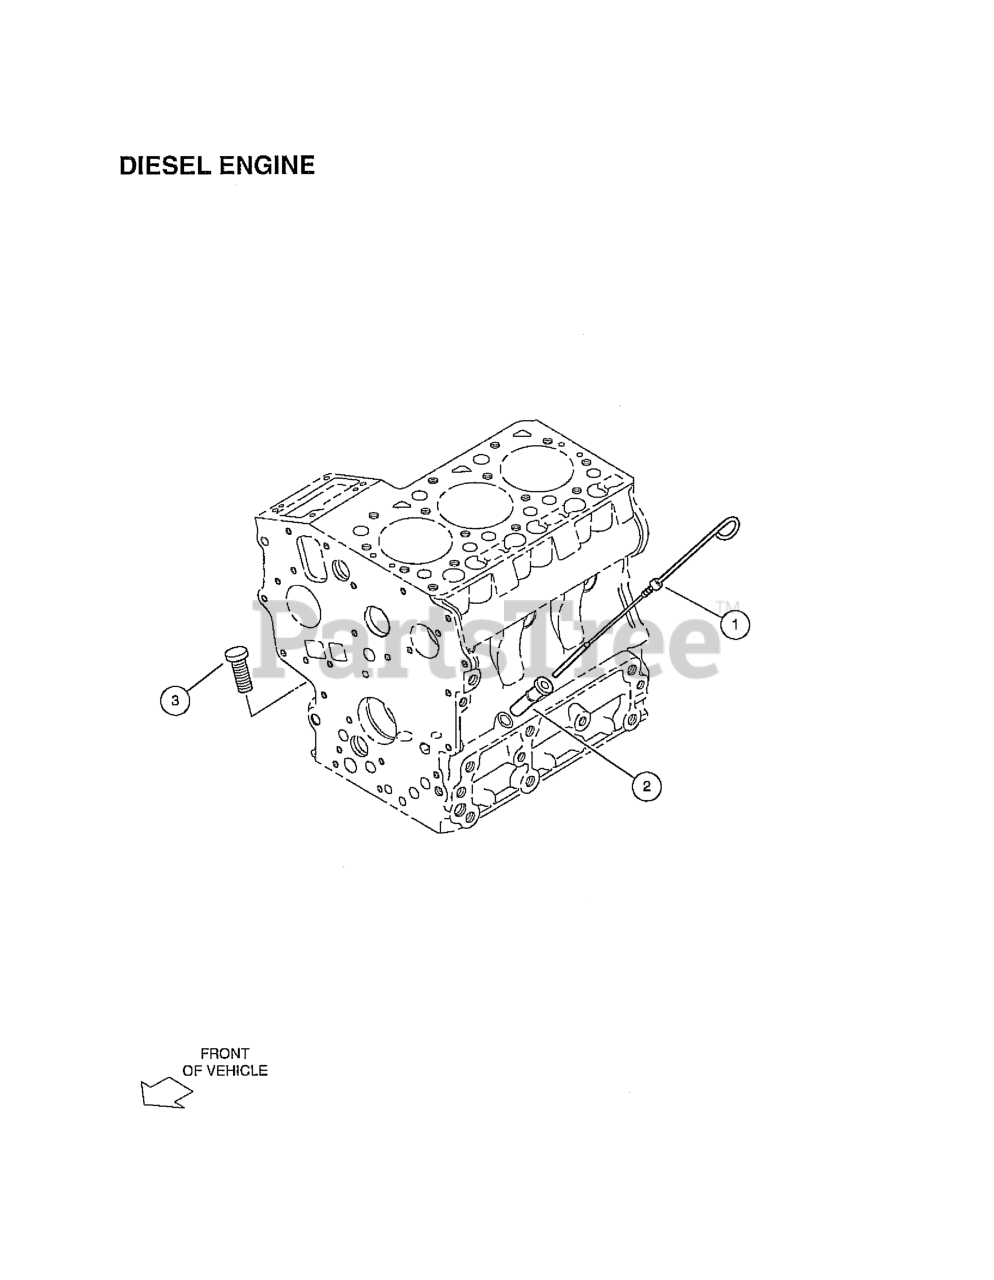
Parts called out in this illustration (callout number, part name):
1	GAUGE, OIL
2	GUIDE, OIL GAUGE
3	PLUG, OIL GAUGE
